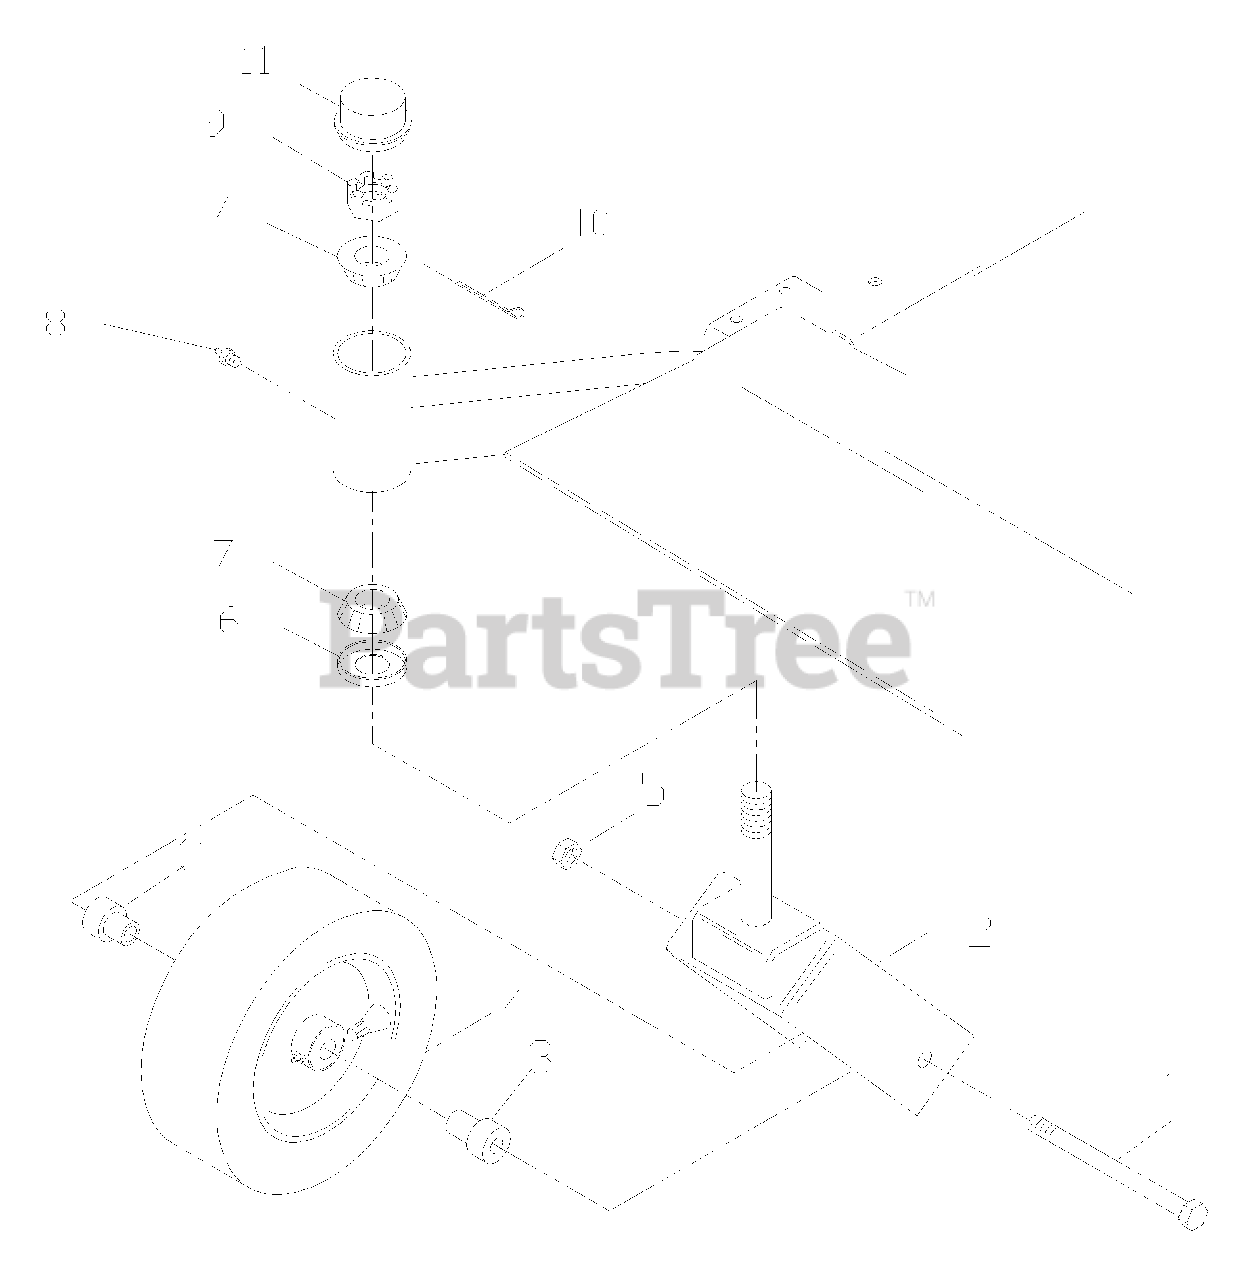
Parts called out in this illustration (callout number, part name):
1	HCS 1/2 X 9.5
2	CASTER YOKE
3	AXLE SPACER
4	TAPERED BEARING
5	NUT 1/2 NYLOC
7	BEARING W/CUP
8	ZERK
9	NUT 1.0 CASTLE
10	COTTER PIN 1/8 X 2
11	GREASE CAP
